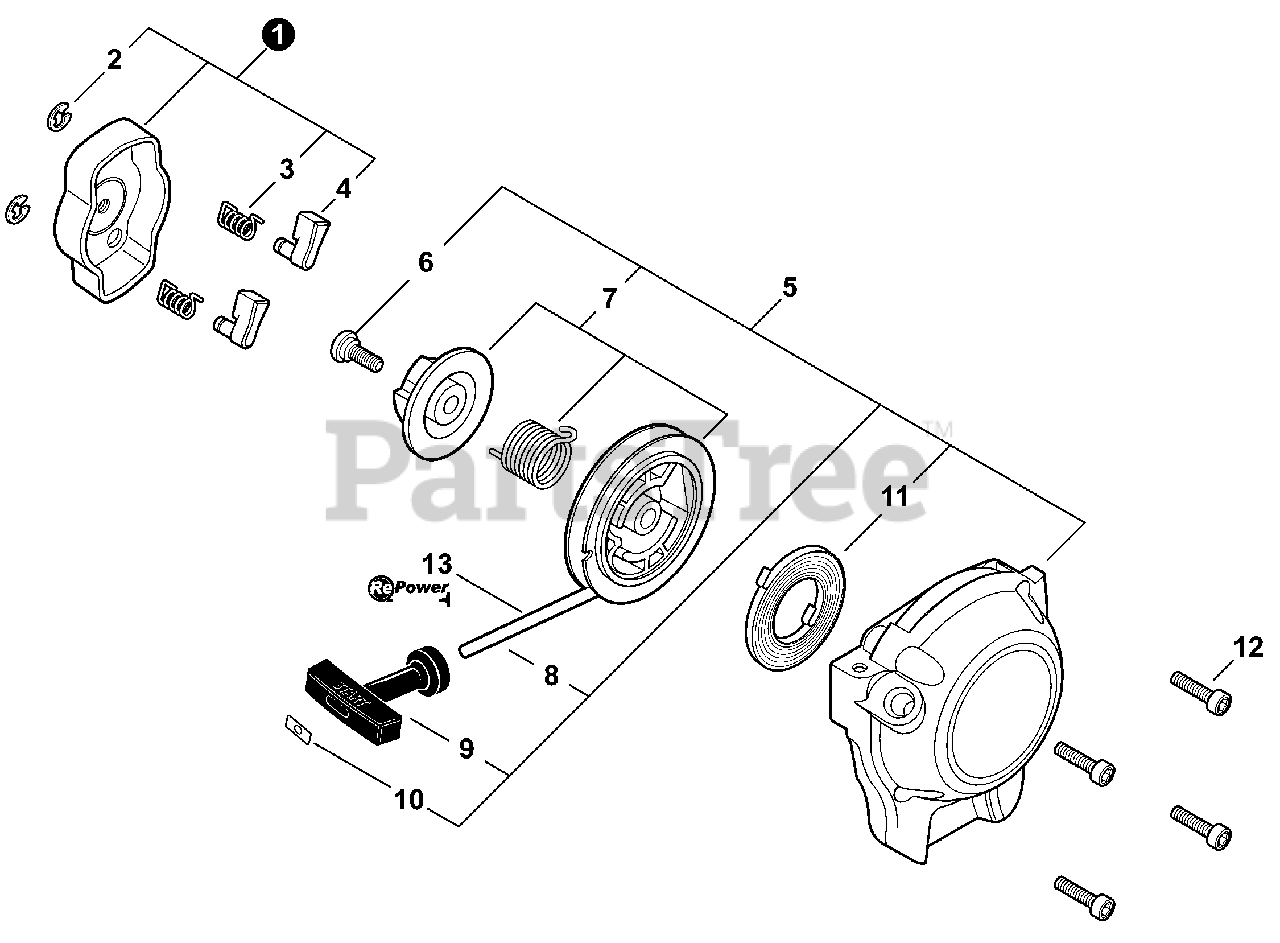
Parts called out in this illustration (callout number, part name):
1	STARTER PAWL ASY
2	E-RING 4
3	SPRING, RETURN
5	STARTER ASY
6	SCREW
7	REEL/CAM PLATE SET
8	ROPE, STARTER - 3X700
9	GRIP, STARTER
10	RETAINER, ROPE
11	SPRING, RECOIL
12	BOLT, TORX 4×16
13	ROPE, STARTER - REPOWER BULK Ø3
